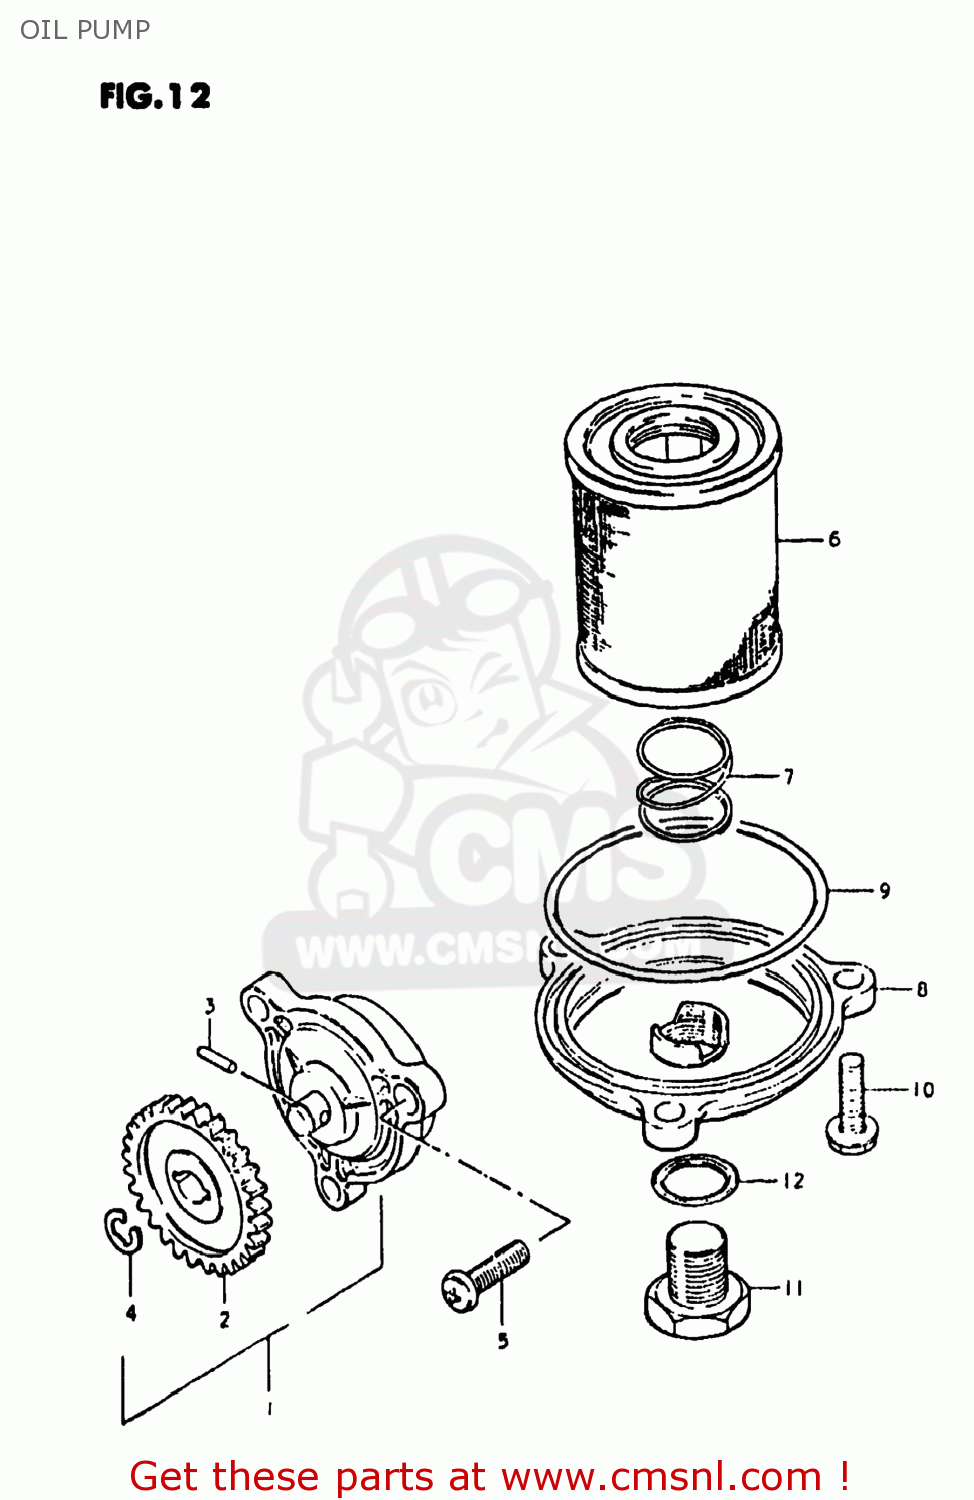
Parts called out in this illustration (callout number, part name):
1	PUMP ASSEMBLY,ENGINE OIL
2	GEAR,OIL PUMP DRIVEN
3	PIN(2.5X11.8)
4	E RING 6MM
5	SCREW
6	STRAINER,OIL
7	SPRING
8	CAP,ENGINE OIL STRAINER
9	O RING(D:2.4,ID:62.6)
10	BOLT,REAR
11	PLUG
12	GASKET(14X19.2X2) (NAS)
